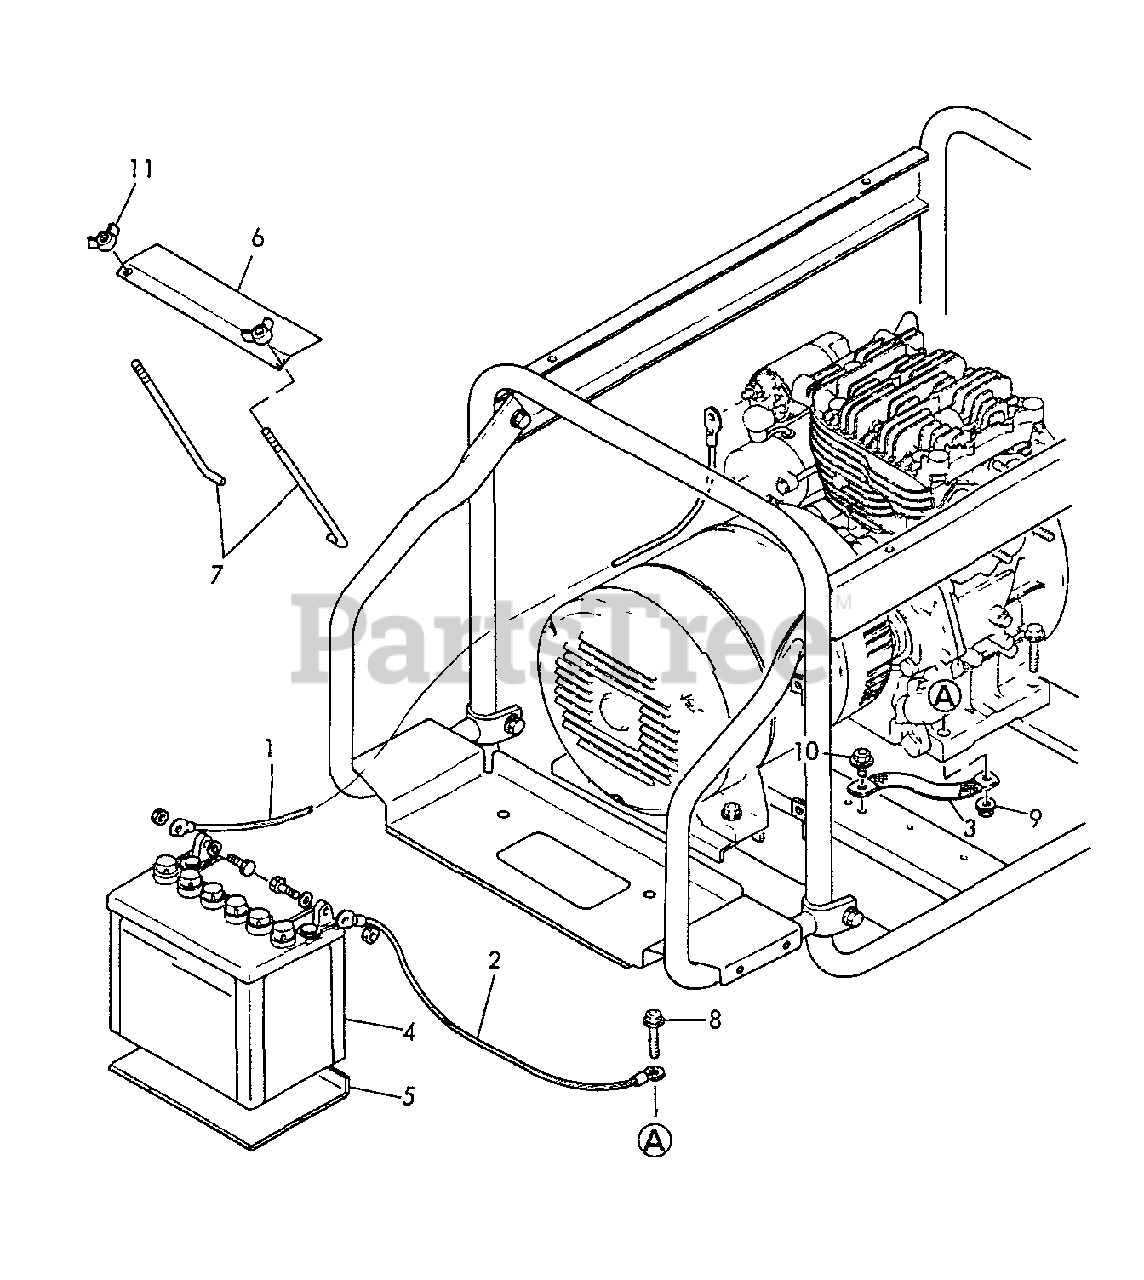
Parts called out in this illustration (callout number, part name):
1	CABLE - ( + )
2	CABLE - ( - )
3	CABLE - ( - )
4	BATTERY 12V - 24AH
5	SHEET, BATTERY
6	RETAINER, BATTERY
7	BOLT, BATTERY
8	BOLT - 8X30 -- PLATED
9	NUT - 8
10	BOLT - 6X8 -- PLATED
11	WINGNUT - 6
